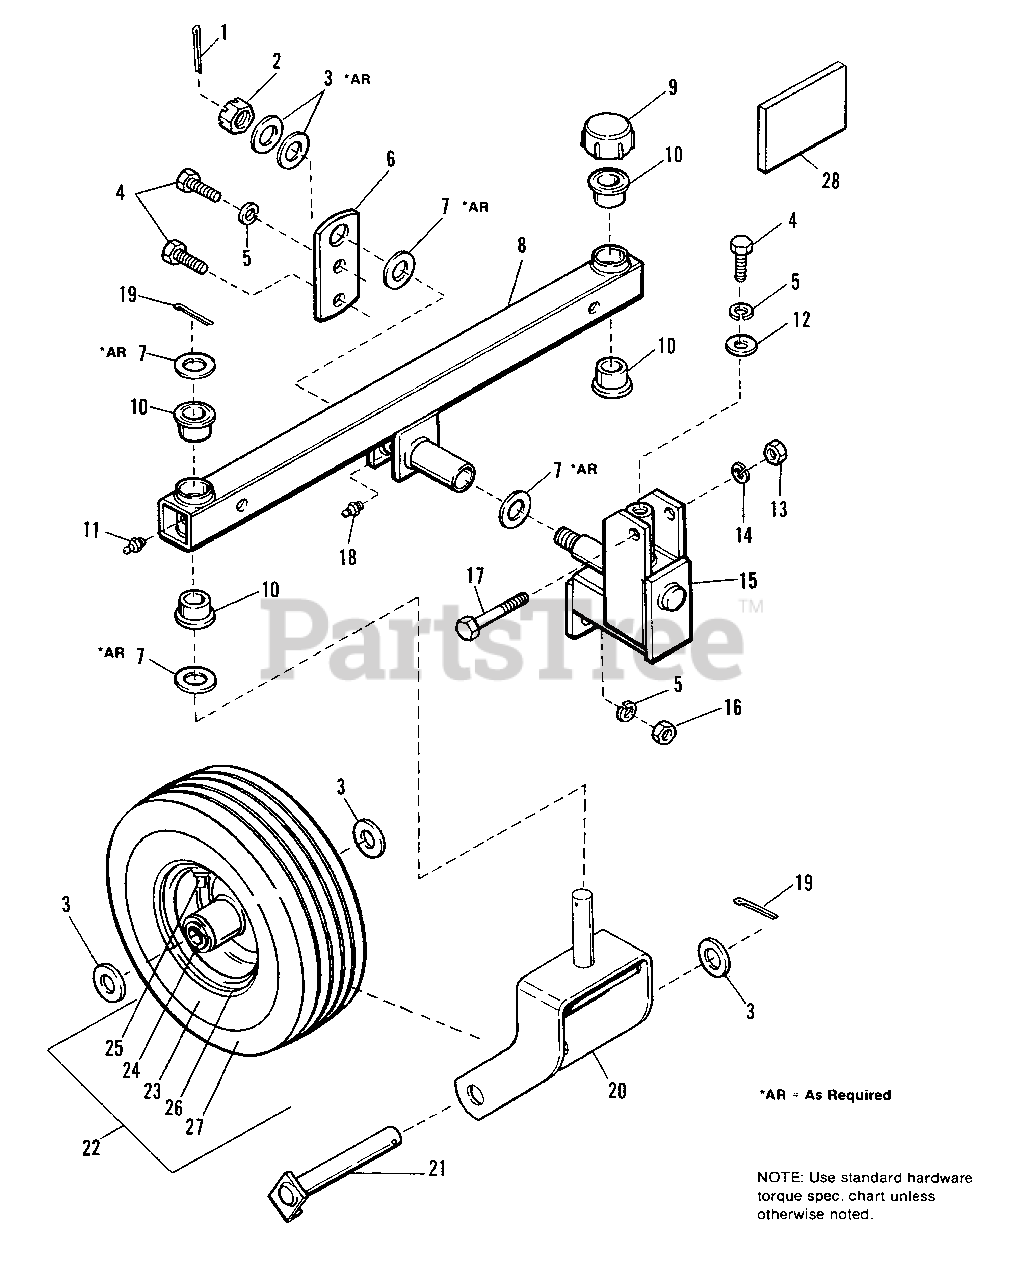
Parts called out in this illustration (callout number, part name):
1	PIN, Cotter
2	NUT, Castle
3	WASHER, 3/4" I.D. x 1" O.D.
4	CAPSCREW, Hex, 1/2-13 x 1-1/4
5	LOCKWASHER, Spring, 1/2
6	PLATE, Support
7	WASHER, 1" I.D. x 1-1/2" O.D.
8	AXLE ASSY.
9	CAP, Plastic
11	FITTING, Grease
12	WASHER, 1/2" I.D. x 1-1/4" O.D.
13	NUT, Hex, 3/8-16
14	LOCKWASHER, 3/8
15	PIVOT SHAFT ASSY.
16	NUT, Hex, 1/2-13
17	CAPSCREW, Hex, 3/8-16 x 3-1/2
18	FITTING, Grease
19	PIN, Cotter
20	CASTER ASSY.
21	PIN AXLE ASSY.
22	WHEEL & TIRE ASSY.
23	TUBE
24	BEARING, Flanged
25	VALVE STEM
26	WHEEL ASSY.
27	TIRE
28	I.D. PLATE
